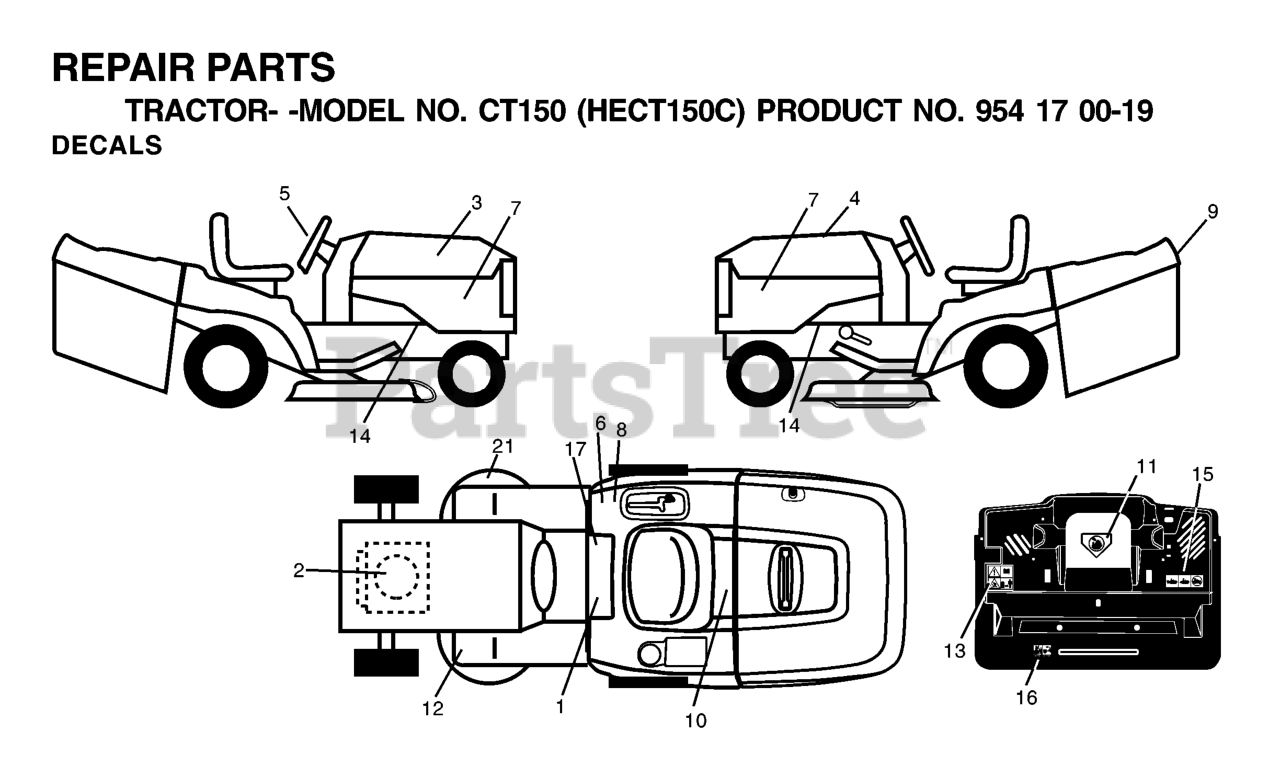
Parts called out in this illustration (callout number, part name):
1	DECAL READ OWNER'S MAN SYMS
2	Decal Hp Engine
3	Decal Hood Rh
4	Decal Hood Lh
5	DECAL.WHEEL.STEERING.HUSQ.PERM
6	DECAL CERTIFICATION
7	DECAL PNL SIDE
8	DECAL EUROPE STANDARD CE
9	DECAL FENDER HUSQ
10	DECAL BTRY SYMBOLS
11	DECAL MOWER CUT/FINGER
12	DECAL
13	Decal Warn Back Plate CRD
16	DECAL
17	DECAL PARK BRAKE
